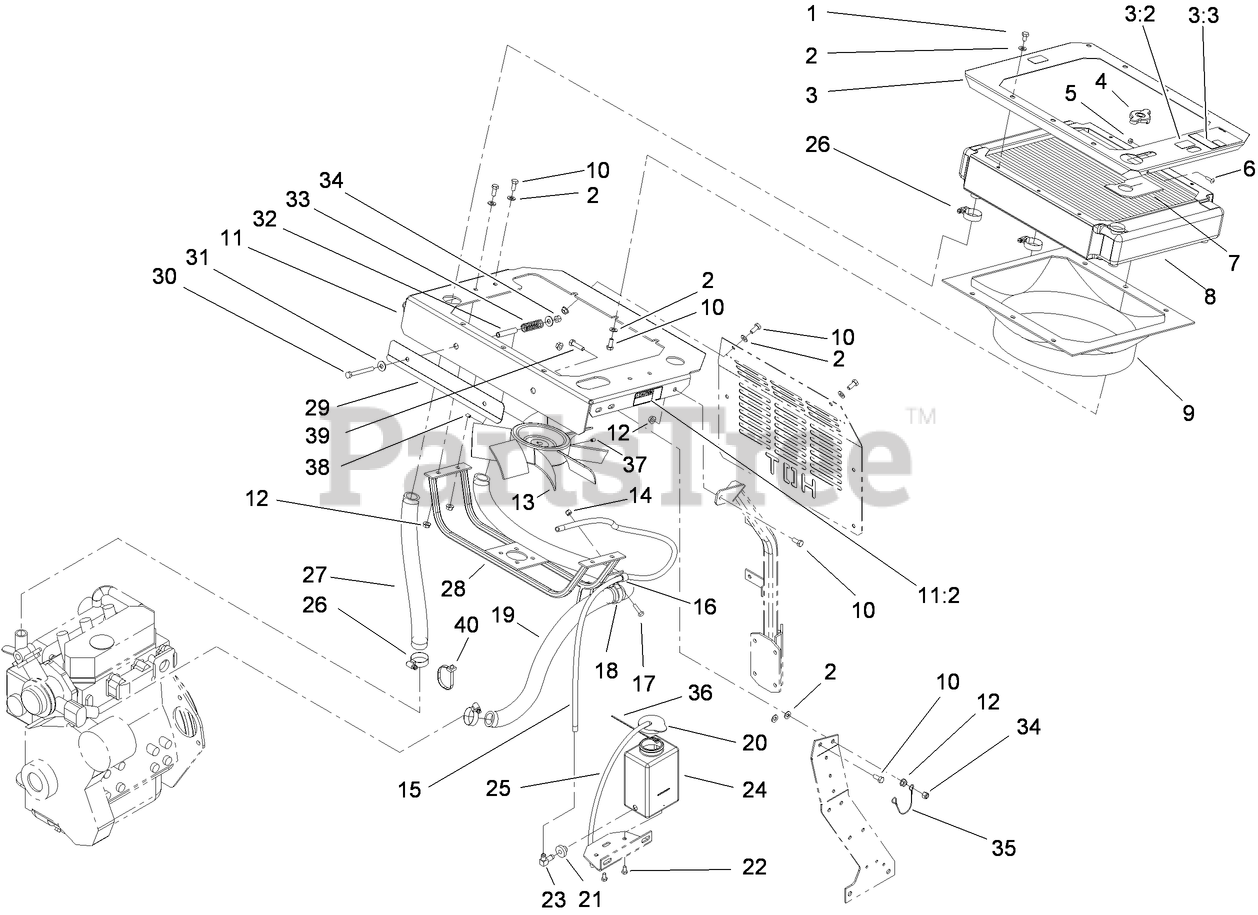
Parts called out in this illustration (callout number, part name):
1	SCREW-HH
2	WASHER-PLAIN
3	PLATE-TRIM, RADIATOR
3:2	DECAL-SURFACE, HOT
3:3	DECAL-COOLANT
4	CAP-RADIATOR
5	NUT-LOCK, NI
6	SCREW-HEAD, TRUSS
7	SHIELD-FILL NECK, RADIATOR
8	RADIATOR
9	SHROUD-COOLING, ENGINE
10	SCREW-HH
11	FAN MOUNTING PLATE ASM
11:2	DECAL-FAN, RADIATOR
12	NUT-HF
14	NUT-LOCK, NI
16	CLIP-LOOM
17	SCREW-HH
18	CLIP-LOOM
19	HOSE-INLET, ENGINE
20	CAP-TANK, OVERFLOW
21	BUSHING-VALVE, FUEL
22	SCREW-HH
23	FITTING-ELBOW
24	TANK-OVERFLOW
26	CLAMP-HOSE
27	HOSE-OUTLET, ENGINE
28	MOUNT-MOTOR, FAN
29	BRACKET-DEFLECTOR, AIR
30	SCREW-HH
31	WASHER-FLAT
32	SPACER
33	SPRING-INDICATOR, REVERSE
34	NUT-LOCK, NI
35	LANYARD
36	TIE-CABLE
37	SCREW-SET
38	SCREW-SET
39	SCREW-HH
40	TIE-PLASTIC
